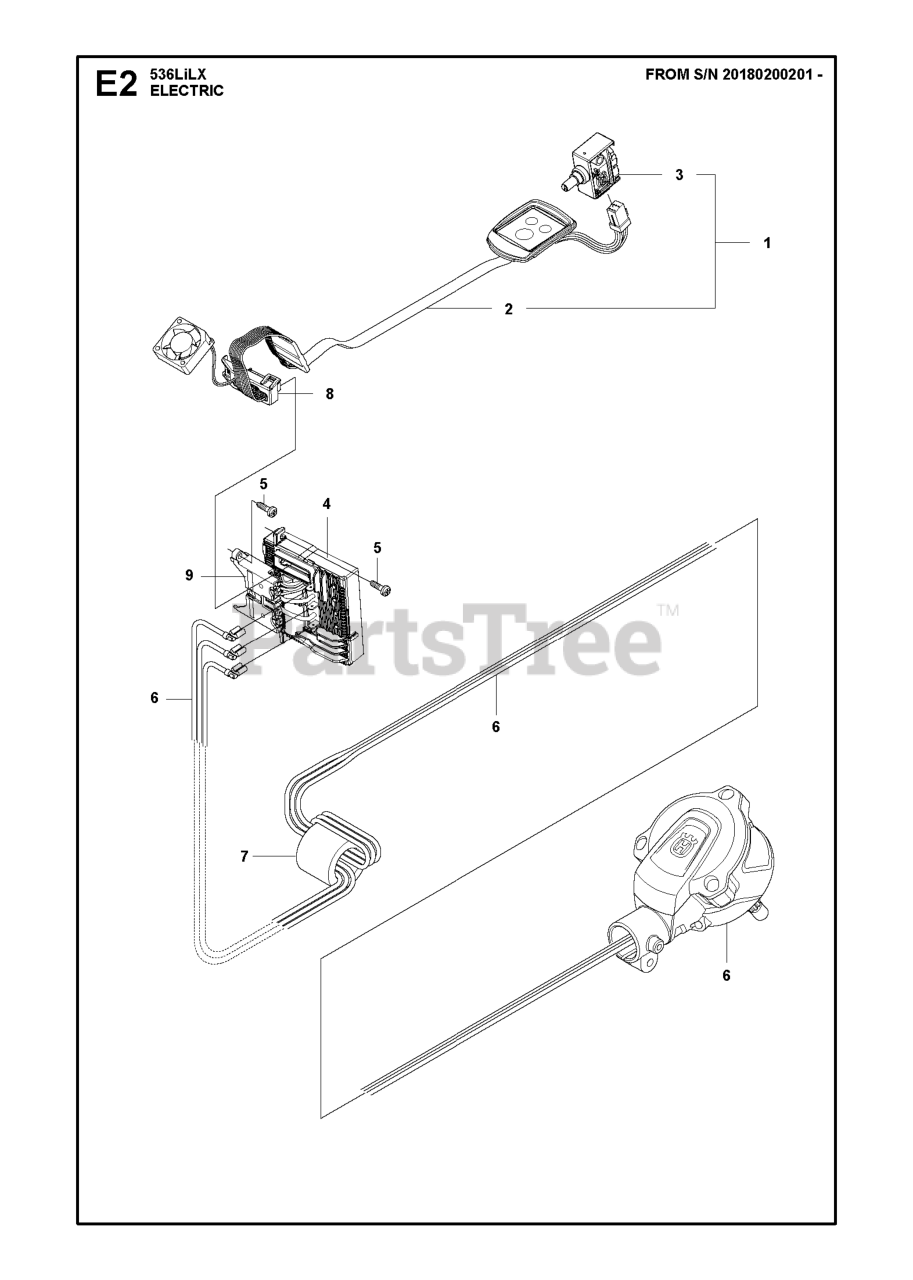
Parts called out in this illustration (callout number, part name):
1	SWITCH KIT BATTERY TRIMMER 536
2	WIRING ASSY MAIN T2
3	TRIGGER SWITCH IPX4
4	CONTROL UNIT
6	MOTOR ASSY BLDC BLADE
7	FERRITE CORE
9	CONNECTOR BATTERY
